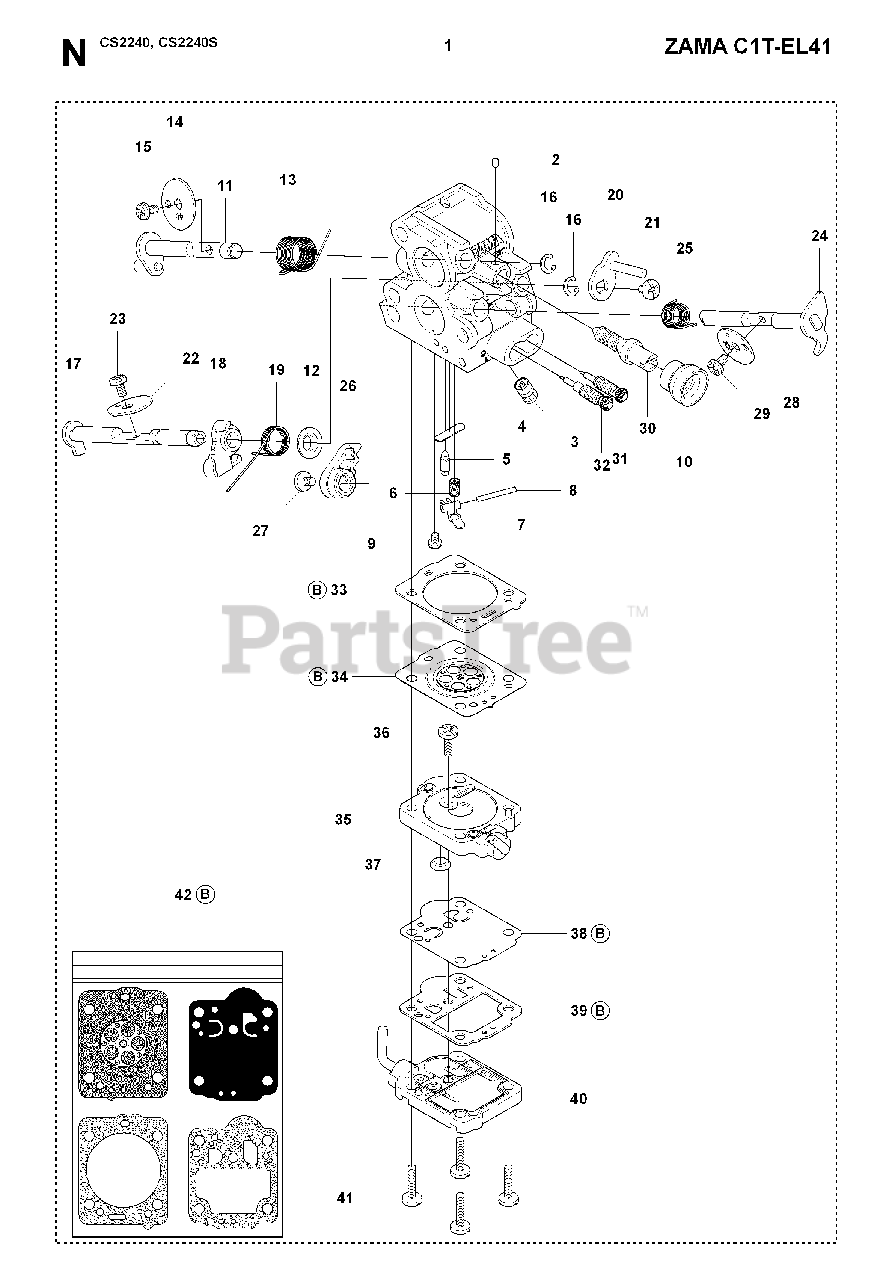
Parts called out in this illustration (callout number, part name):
1	CARBURETOR
3	NOZZLE ASSY
5	INLET NEEDLE
6	SPRING
8	PIN FULCRUM
10	CAP ZAMA 0051034
11	SHAFT ASSY
12	COLLAR ZAMA 005020
17	SHAFT ASSY
24	SHAFT ASSY
34	DIAPHRAGM
38	DIAPHRAGM
42	GASKET KIT
